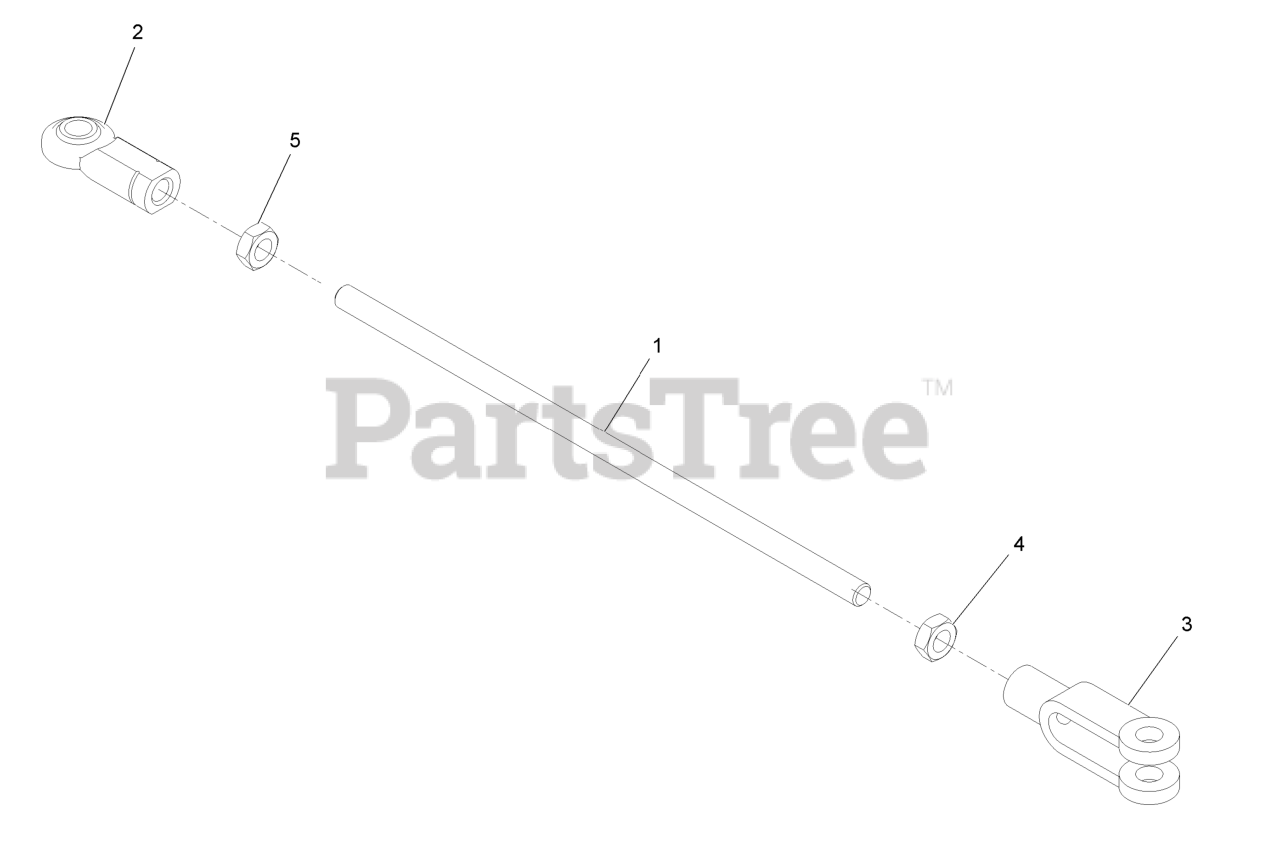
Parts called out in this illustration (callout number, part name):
1	Rod-Brake Linkage
2	Joint-Ball End, .38X.38Fe LH
3	Yoke-Linkage, Brake
4	Nut-Jam 3/8-24
5	Nut-Jam 3/8-24 LH
